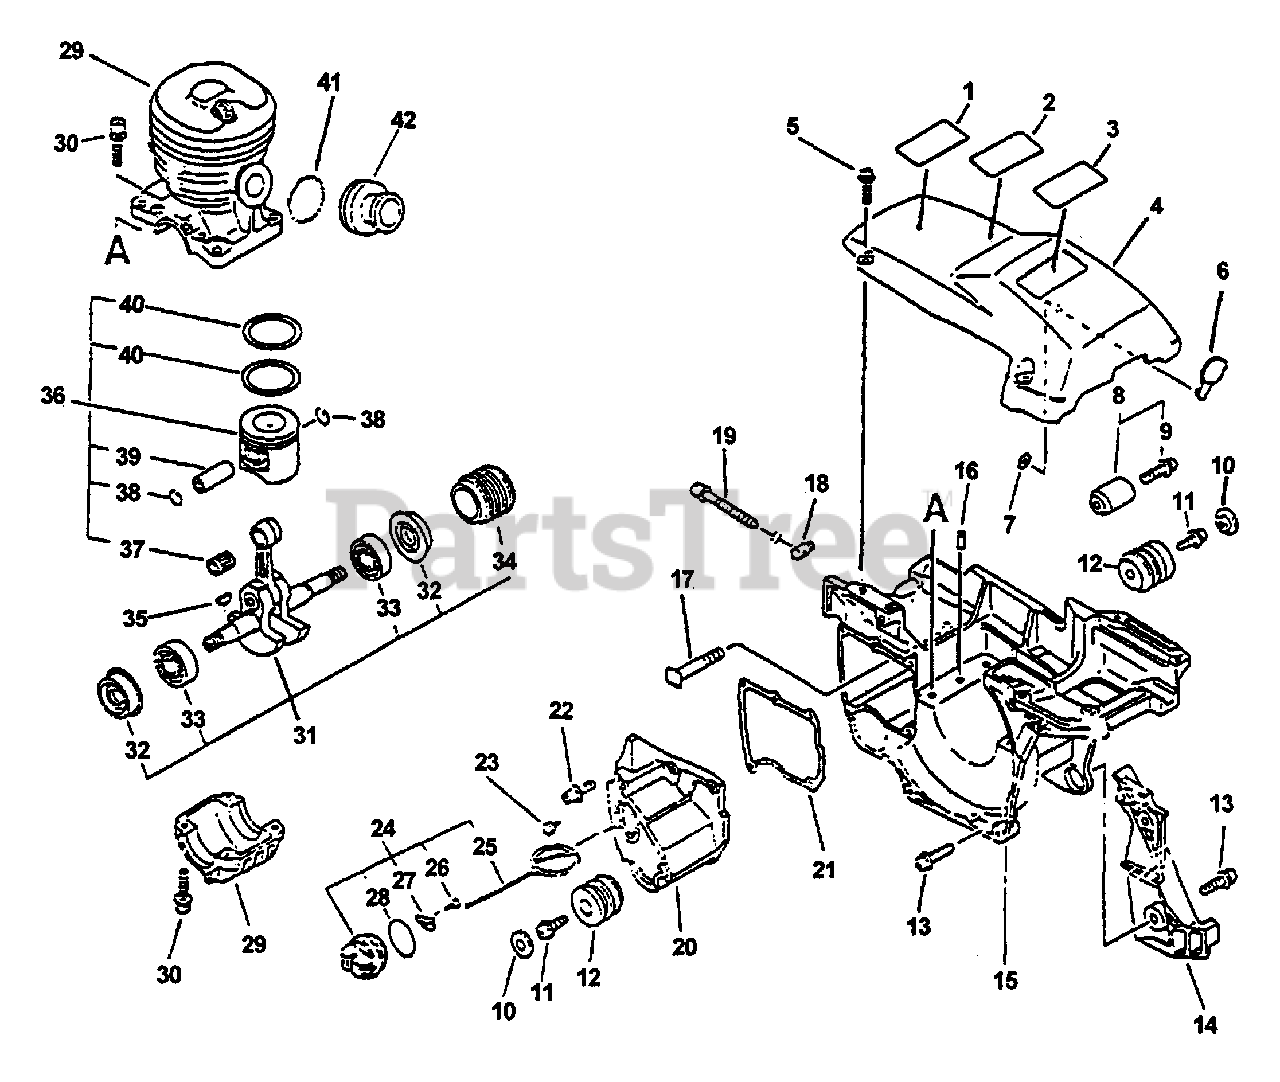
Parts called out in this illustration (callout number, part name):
1	LABEL - KICK BACK
3	LABEL, CS-4400
4	COVER, ENGINE
6	PLATE, WIND PROOF
7	PUSHNUT - 4
8	CHAIN CATCHER KIT
9	SCREW 5×18
10	CAP, CUSHION
12	CUSHION 5
13	SCREW 5×16
15	COVER, ENGINE
16	PIN, LOCATING 4
17	STUD, GUIDE BAR 8
18	TENSIONER, CHAIN
19	SCREW, CHAIN TENSION
20	OIL TANK ASSY
21	GASKET, OIL TANK
22	BOLT 4×16
23	VENT ASSY
24	CAP ASSY, OIL
25	CONNECTOR, CAP L= 60 MM
26	SCREW, TAPPING 3×8
27	RETAINER, CONNECTOR
29	CRANKCASE KIT
30	BOLT 5×22
31	CRANKSHAFT ASSY
32	SEAL, OIL
33	BEARING, BALL - 6201 C3
34	GEAR, WORM
35	KEY, WOODRUFF
36	PISTON KIT
37	BEARING, NEEDLE 9
38	RING, RETAINING
39	PIN, PISTON
40	RING, PISTON
42	ADAPTOR, INTAKE
